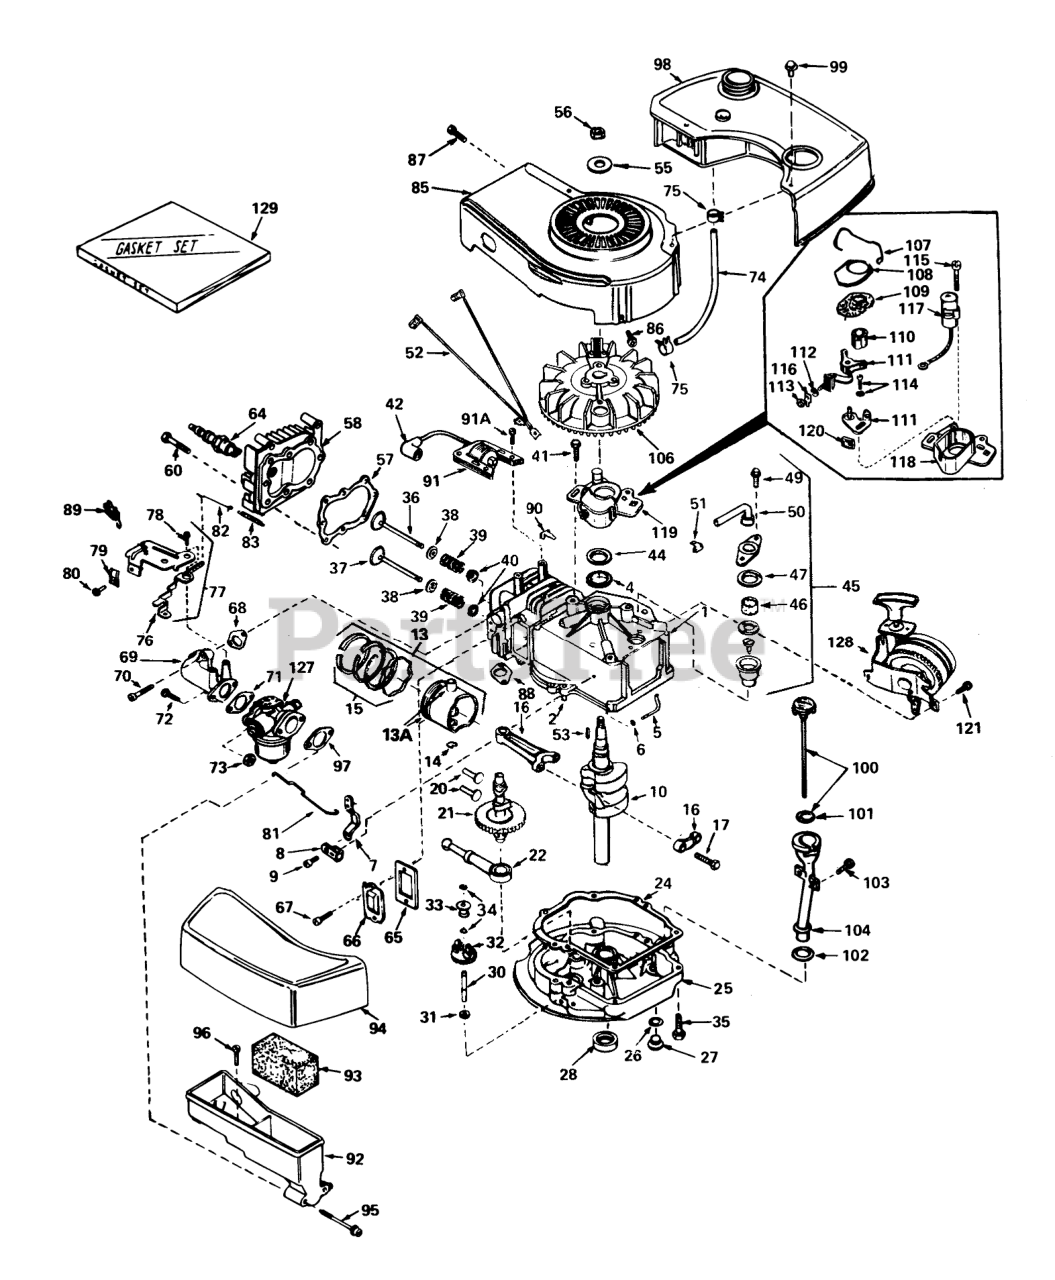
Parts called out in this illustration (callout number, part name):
1	Cylinder Assy. (Incl. Ref. #2, 4 & 121)
2	Pin-Dowel
4	Seal-Oil
5	Rod, Governor (Incl. Ref. #6)
6	Washer-Flat
7	Governor Lever
8	Clamp-Lever, Governor
9	Screw
10	Crankshaft
13	Piston, Pin & Ring Assy. (Incl. Ref. #13A, 14 & 15) (Std.)
13	Piston, Pin & Ring Assy. (Incl. Ref. #13A, 14 & 15) (.010 oversize)
13	Piston, Pin & Ring Assy. (Incl. Ref. #13A, 14 & 15) (.020 oversize)
13A	Piston & Pin Assy. (Incl. Ref. #14) (Std.)
13A	Piston & Pin Assy. (Incl. Ref. #14) (.010 oversize)
13A	Piston & Pin Assy. (Incl. Ref. #14) (.020 oversize)
14	Ring-Retaining, Piston Pin
15	Ring Set Piston (Std.)
15	Ring Set Piston (.010 Oversize)
15	Ring Set Piston (.020 Oversize)
16	Rod Assy., Connecting (Incl. Ref. #17)
17	Bolt-Rod, Connecting
20	Lifter-Valve
21	Camshaft(Mech.Comp. Release)
22	Oil Pump ASM
24	Gasket, Mounting
25	Flange Assy., Mounting (Incl. Ref. #26 thru 30)
26	Gasket-Oil Drain
27	Plug Oil Drain
28	Seal Oil
30	Shaft-Governor
31	Washer-Flat
32	Gear Assy., Governor (Incl. Ref. #31)
33	Spool-Governor
34	Ring-Retaining
35	Screw (1/4-20 x 1-1/4)
36	Valve Intake (Std.)(Incl. #38, 39 & 40)
36	Valve, Intake (1/32" oversize) (Incl. Ref. #38, 39 & 40)
37	Valve, Exhaust (Std.) (Incl. Ref. #38, 39 & 40)
37	Valve, Exhaust (1/32" oversize) (Incl. Ref. #38, 39 & 40)
38	Cap-Upper Valve Spring
39	Spring-Valve
40	Cap-Valve, Spring
42	Cover-Spark Plug
44	Gasket Stator
45	Breather Assy. (Incl. Ref. #46 47, 49, 50 & 51)
46	Element-Breather
47	Gasket-Breather
49	Screw (10-24 x 9/16)
50	Tube, Breaker
51	Clip, Breather
52	Wire Ground
53	682488 LB GRASS HI-
55	Washer-Belleville
56	Nut-Flywheel
57	63573 GIL 42 SNWTHW
58	Head-Cylinder
60	Screw (5/16-18x1-1/2)
64	Plug, Spark (J17LM or equiv.)
64	Plug, Spark (Champion RCJ-8)
65	Gasket-Breather
66	Cover-Valve
68	Gasket, Intake
69	Pipe, Intake
70	Screw (1/4-20 x 1)
71	Gasket-Carburetor
72	Screw (1/4-28 x 7/8)
73	Nut and Lock Washer (1/4-28)
74	Line-Fuel
75	Clamp-Line, Fuel
76	Lever Control
77	Control Assy., Speed (Incl. Ref. #76, 78 & 89)
78	Screw, Hex Washer Hd Shoulder Self-Tap
79	Conduit
80	Screw (10-32 x 3/8)
81	Link-Throttle
82	Link Governor Spring
83	Spring Governor
85	Housing Blower
86	Screw
87	Screw (10-24 x 9/16)
88	Gasket Exhaust
89	Terminal
90	Clip-Wire
91	Lamination & Coil Assy. (Incl. Ref. #42)
91A	Screw
92	Body Air Cleaner
93	Filer, Air
94	Cove, Air Cleaner
95	Screw Fil Hd.
96	Screw, Hex Hd.
97	Gasket-Air Cleaner
98	Tank, Fuel
99	Screw (10-32 x 35/64)
100	Dipstick, Oil (Incl. Ref. #101) (Twist Lock)
103	Screw (10-32 x 1/2)
104	Tube-Oil Fill
106	FIywheel
107	Spring Breaker Box
108	Cover-Dust
109	Gasket-Dust Cover
110	Cam-Breaker
111	Breaker Assy.
114	Breaker Screw
115	Condenser Screw
116	Terminal, Ground
117	Condenser
118	Stator Plate
119	Stator Assy. (Incl. Ref. #107, 111 thru 118 & 120)
120	Felt,Cam Wiper
121	Screw (1/4-20 x 1/2)
127	Carburetor (Incl. Ref. #71)
128	Starter, Side Mount
129	53024/VAR.16HP O/P
